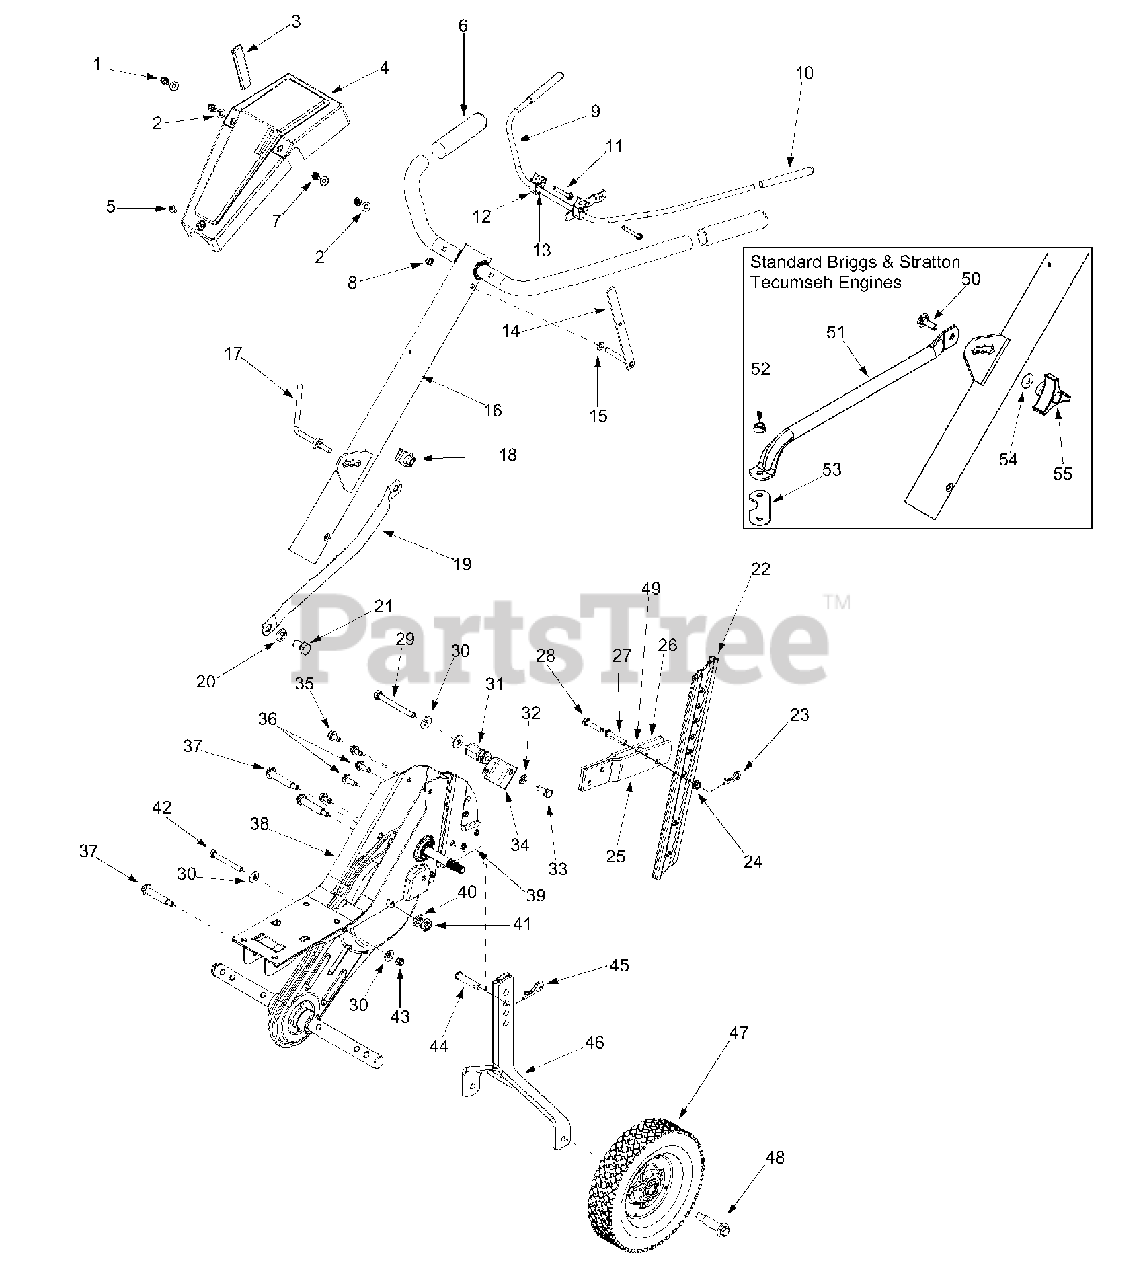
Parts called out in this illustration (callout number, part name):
1	Acorn Lock Nut 1/4-20
2	Flat Washer .271" I.D. x .630" O.D.
3	Reverse Handle Grip
4	Handle Cover w/o throttle
5	Truss Mach. Scr. #10 x 1/2" Lg.
6	Grip-Handle
7	Hex Nut 1/4-20 Gr.2
8	Cap Speed Nut
10	Grip-Clutch
11	Hex Bolt 1/4-20 x 2.25" Lg. Gr.5
12	Clutch Handle Holder
13	Flat Washer .385" I.D. x .62" O.D.
15	Flat Washer .344" I.D. x .62" O.D.
18	U Nut 5/16-18
21	Hex Bolt 1/2-20 Gr. 5
23	Cotter Pin
24	Hex Flange L-Nut 5/16-18 Thd. Gr.5
27	Clevis Pin
28	Hex Bolt 5/16-18 x 1.5" Lg.
29	Hex Bolt 5/16-18 x 3" Lg.
30	Wash. Bell. .340" I.D. x .872" O.D.
31	Spec. Hex Nut
32	L-Wash. 5/16" I.D.
33	Hex Bolt 5/16-18 Gr. 5
35	Hex Washer Screw 5/16-18 x .62" Lg.
36	Hex Wash. Hd. TT-Tap Scr.
37	Shdl. Bolt 5/16-18
40	Lock Washer 7/16
41	Jam Nut 7/16-20 Gr. 2
42	Hex Bolt 5/16-18 x 2.75" Lg.
43	Hex Nylon Nut 5/16-18 Thd.
44	Clevis Pin
45	Cotter Pin
47	Wheel Ass'y 8" x 1.75"
48	Shoulder Screw .496 I.D. x 1.445 O.D.
49	Spacer
50	Carr. Bolt 5/16-18 x 1
53	Engine Brkt.
54	Bell. Wash. .34" I.D.
55	Hand Knob
